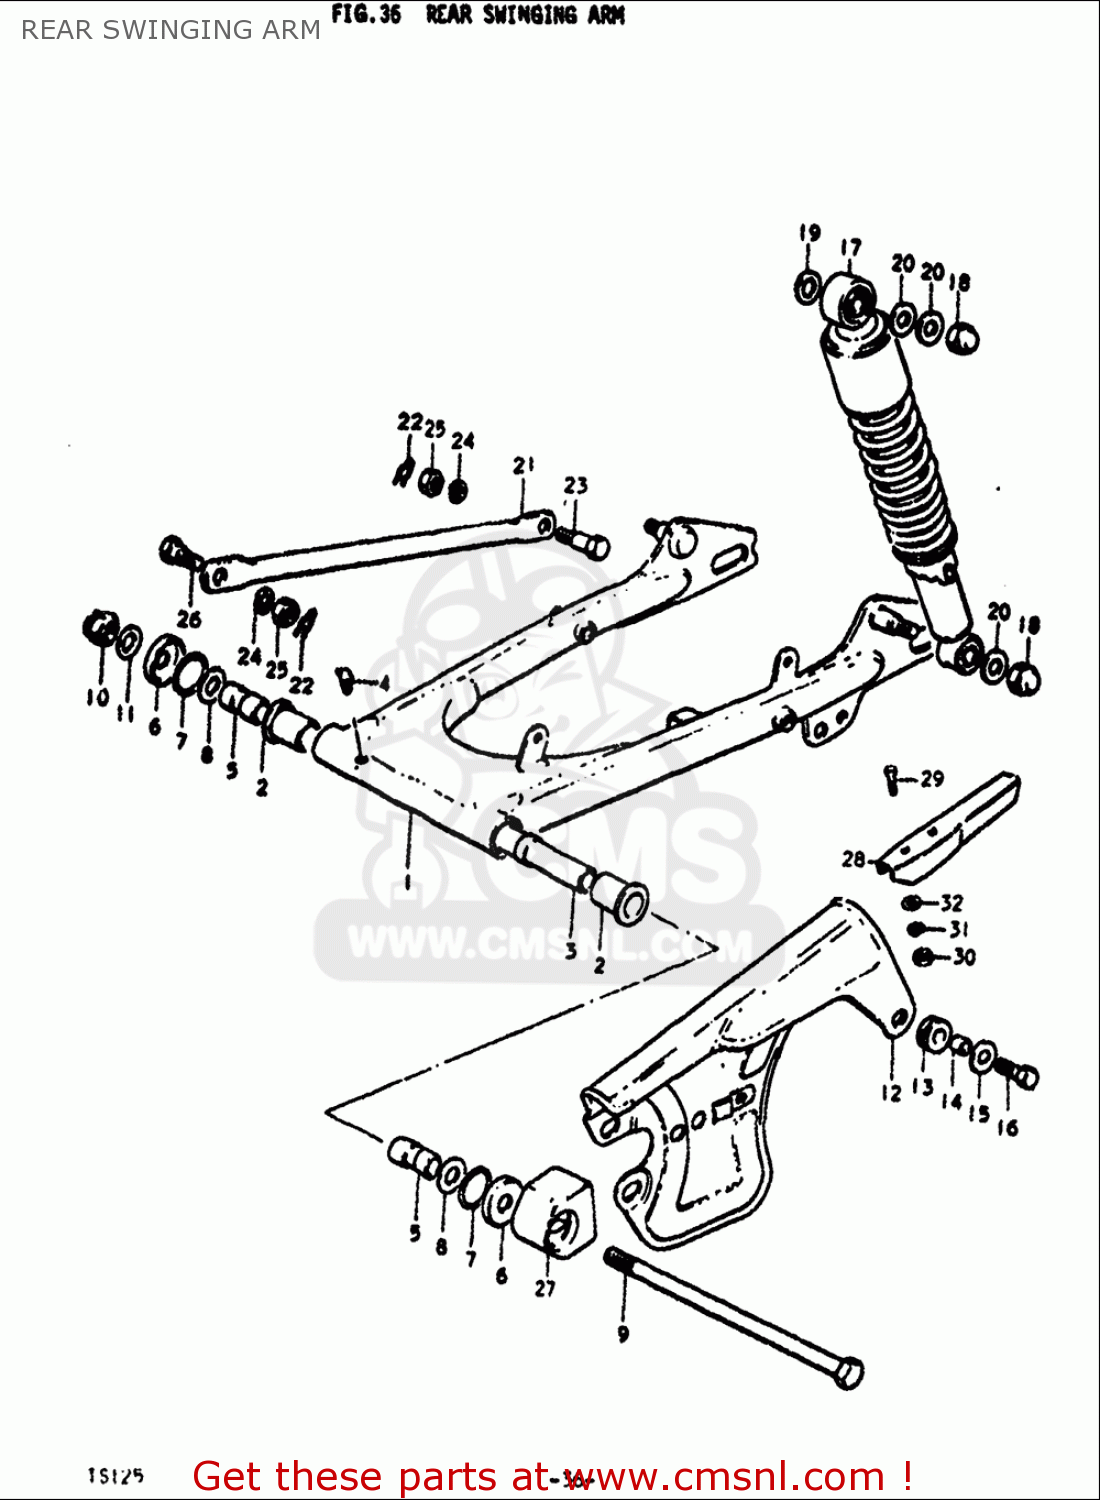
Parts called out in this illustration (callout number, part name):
2	BUSH
3	SPACER,SWING ARM,CENTER
4	NIPPLE,GREASE
5	SPACER,RR SWGARM PIVOT
6	COVER,SWGARM BUSH DUST SEAL
7	O RING(D:2,ID:24.5)
8	WASHER(12.5X24X2.3)
11	WASHER
13	CUSHION
14	SPACER,6.5X9X7
15	WASHER(6.5X20X1.2)
16	BOLT
18	NUT
19	WASHER
20	WASHER (10.5X24X2.3)
21	LINK,RR TORQUE
22	RETAINER,SNAP
23	BOLT(8X26.5)
24	WASHER,LOCK
25	NUT
26	BOLT(8X22)
27	BUFFER,CHAIN TOUCH DEFENSE
29	BOLT
31	WASHER,LOCK
32	WASHER
